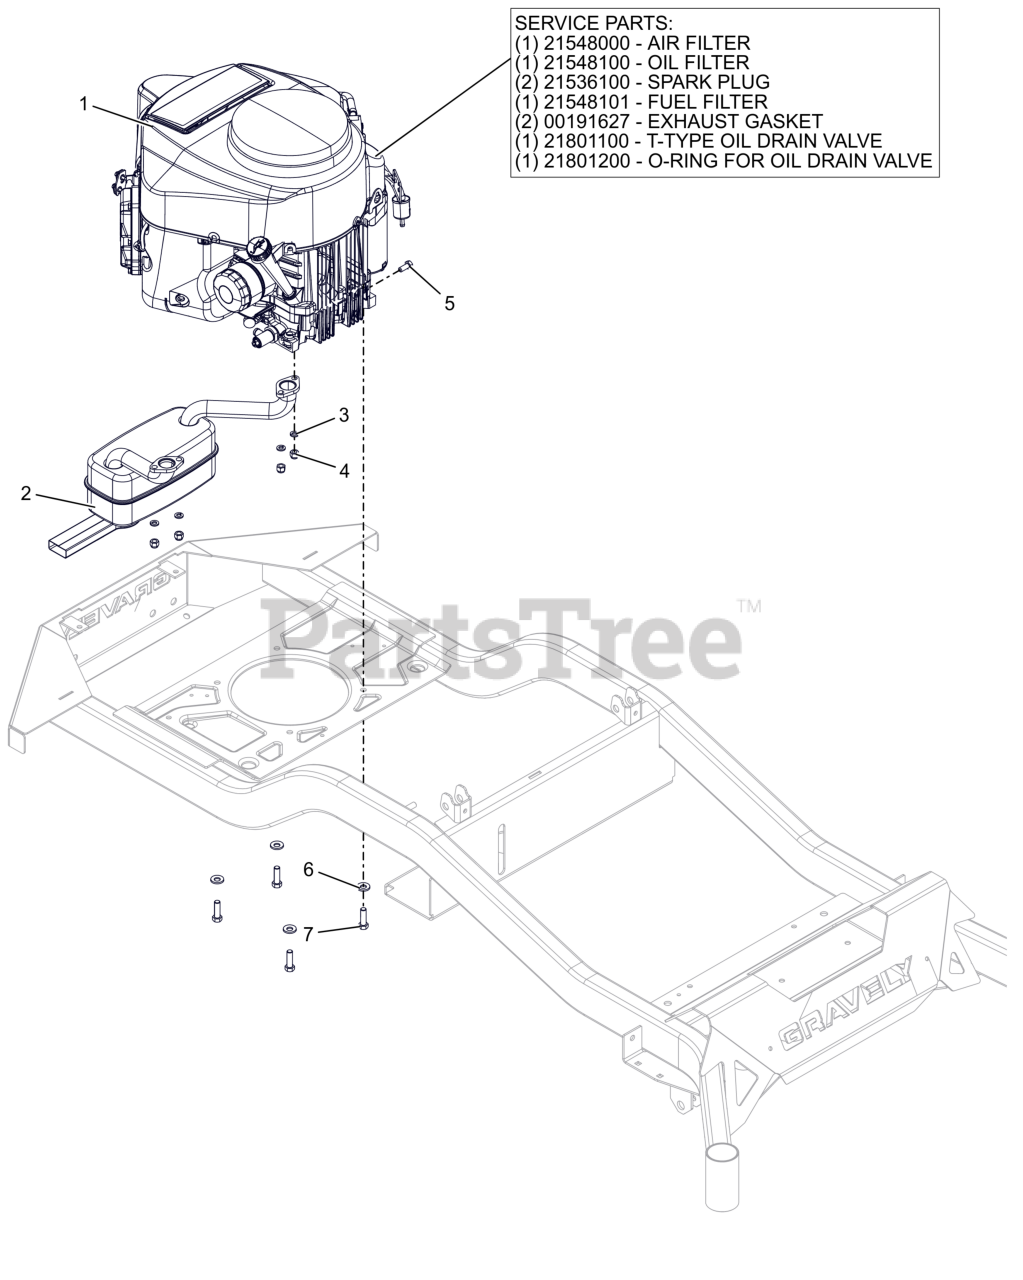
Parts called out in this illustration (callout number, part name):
1	ENGINE, KAWASAKI FR651V
1	AIR FILTER, KAWASAKI FR
1	OIL FILTER, KAWASAKI FR
1	PLUG, SPARK
1	FUEL FILTER-KAWASAKI FR
1	GASKET, MUFFLER S/O
1	VALVE- T-TYPE OIL DRAIN
1	O-RING- OIL DRAIN VALVE
2	MUFFLER, KAWASAKI
3	WSHR,LK-REG .312X.078 ZCC
4	NUT,NYL M8-1.25 G8.8 ZCC
5	BLT, HEX M8-1.25X20 G8.8 ZCC
6	WASHER, 3/8" SPRING DISC
7	BLT, HEX .38-16X1.25 G5 ZCC NT
